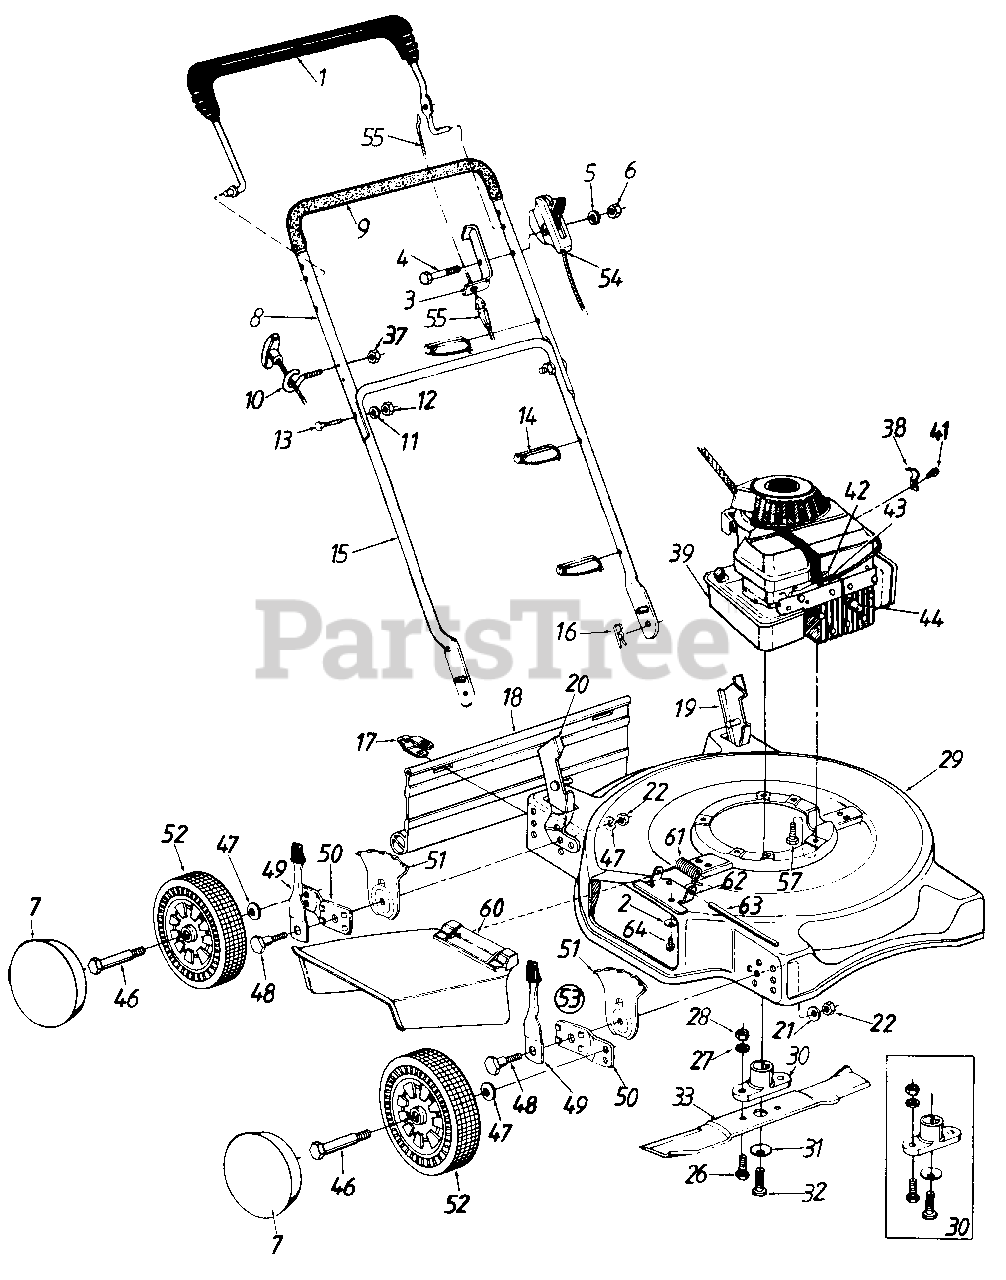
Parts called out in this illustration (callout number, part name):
1	Control Handle Ass'y.
2	Bell-Wash. 1/4" I.D.
3	Cable Brkt.
4	Hex Bolt 1/4-20 x 1.875" Lg.
5	Spr. Wash. 1/4" I.D.
6	Hex Nut 1/4-20 Thd.
7	Hub Cap
9	Foam Grip
10	Rope Guide
11	L-Wash. 5/16" I.D.
12	Hex Nut 5/16-18 Thd.
13	Curved Carriage Bolt 5/16-18 x 1.38" Lg.
14	Cable Tie
15	Lower Handle
16	Hairpin Cotter
17	Hinge Clip
18	Rear Flap
19	Handle Bracket Ass'y.-L.H.
20	Handle Bracket Ass'y.-R.H.
21	Bell-Wash. .39" I.D. x 1.38"
22	Hex Nut 3/8-16 Thd.
26	Hex Bolt 3/8-24 x 1" Lg.
27	L-Wash. 3/8" I.D.
28	Hex Nut 3/8-24 Thd.
31	Bell-Wash..39" I.D.
32	Hex Bolt 3/8-24 x 1.5" Lg.
33	20" Blade
37	Hex L-Nut 1/4-20 Thd.
38	Cable Clamp
39	Engine
41	Hex B-Tap Scr. #10 x .38"
43	Hex AB-Tap Scr. #8 x .38"
44	Spark Plug Boot
46	Axle Bolt
47	Bell-Wash. .400" I.D. x .88"
48	Shld. Bolt .50" Dia. x .357"
49	Spring Lever Ass'y. w/Knob
51	Height Adj. Plate
52	Wheel Ass'y. Comp.
53	Height Adj. Ass'y. Comp.- 0 R.F. & L.R.
54	Throttle Control Ass'y. Comp.- 0 51 .6211
55	Control Cable-36"
57	Hex L-Wash. Hd. Scr. 3/8-16 x 1.0" Lg.
60	Chute Deflector Ass'y.
61	Torsion Spring
62	Adapter Plate
63	Hinge Pin
64	Hex Self-Tap Scr. 1/4-20 x .5" Lg.
17036-0483	DECK ASSEMBLY-20IN - CHARCOAL GRAY (0483)
17036-0629	DECK ASSEMBLY-20IN - SILVER FLAKE (0629)
